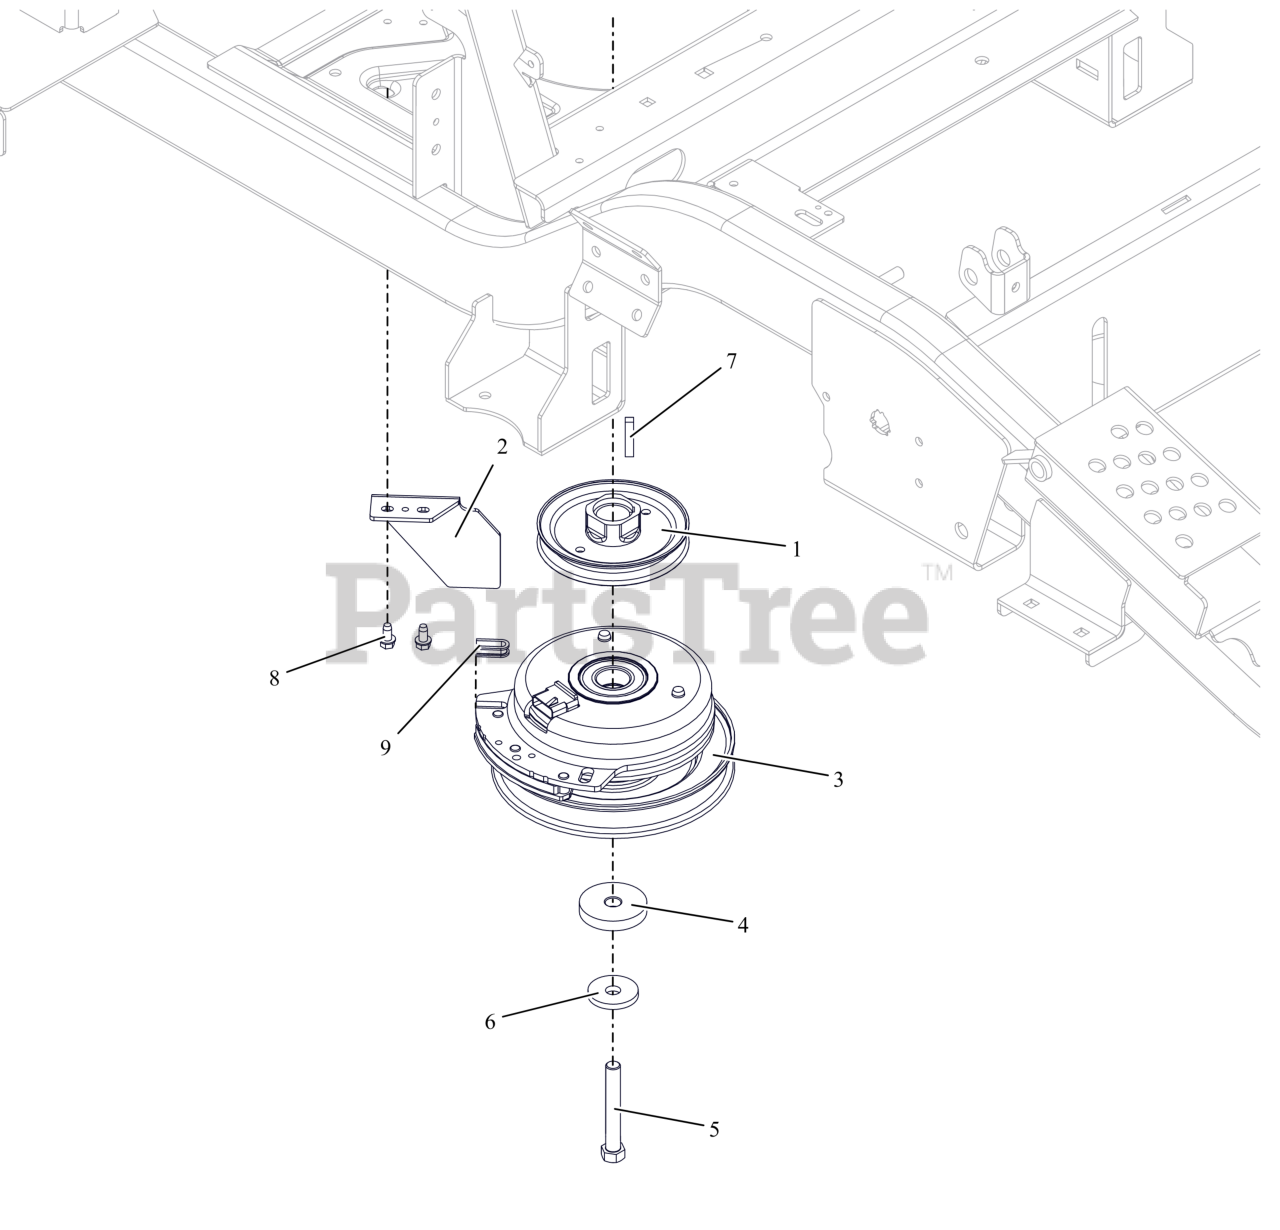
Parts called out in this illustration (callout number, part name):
1	WLDMT-PULLEY-4.50ODX1.003
2	BRKT- CLUTCH STOP HD
3	CLUTCH- WARNER 1.00 HD-PTZ
4	SPACER, .474/.459X2.00X.350
5	BLT, HEX 0.4375-20X3 G8 ZCC NT
6	WASHER, 7/16" SPRING DISK
7	KEY-SQ .25 X 1.25 X .25 SAE
8	SCR-TAP .25-20X.50 HWH ZCC
9	BSHG, CLUTCH
